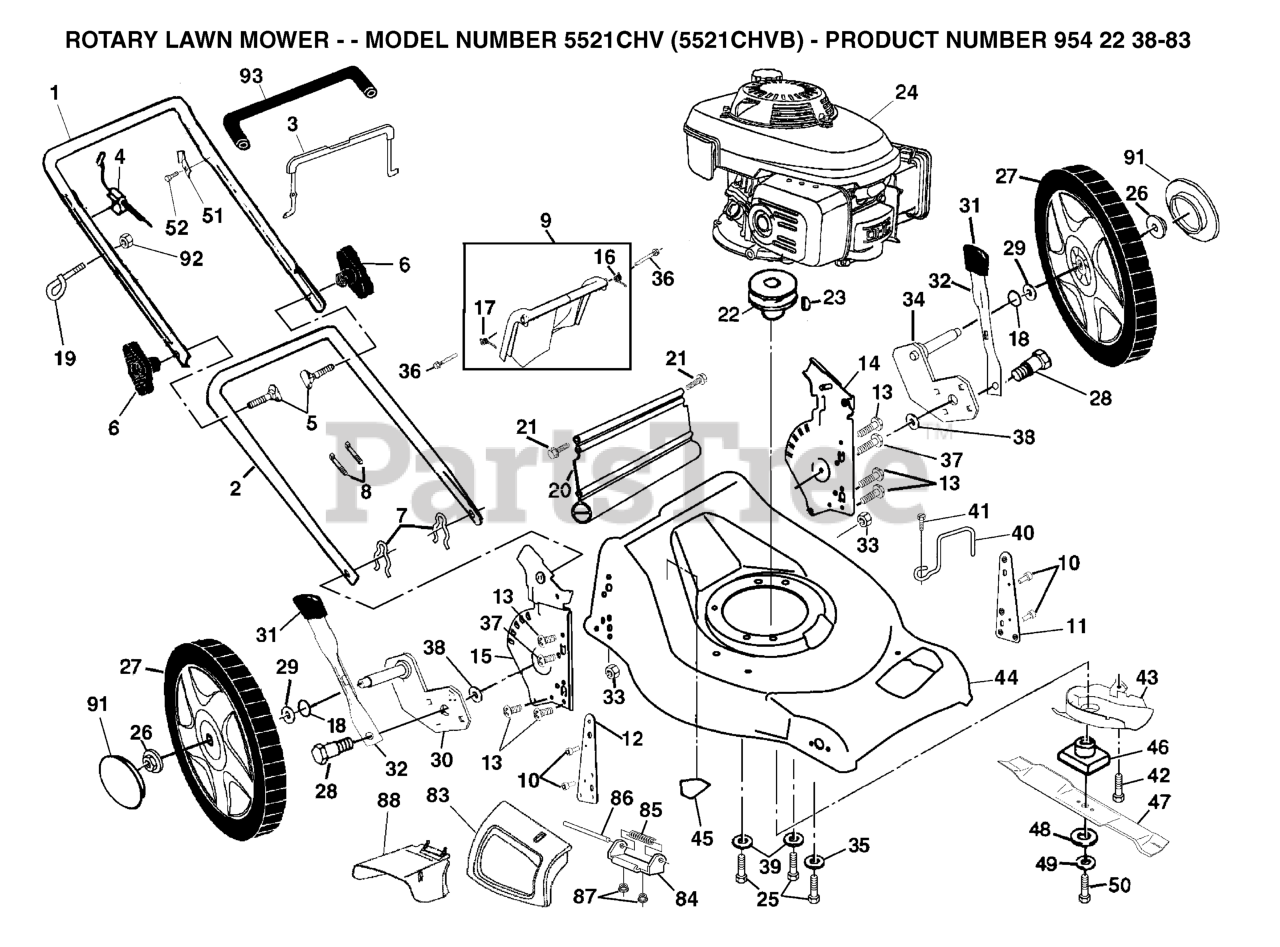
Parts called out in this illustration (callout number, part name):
1	UPPER HANDLE W/ GRIP
2	LOWER HANDLE
4	ENGINE ZONE CONTROL CABLE
5	HANDLE BOLT
7	HAIRPIN COTTER
8	TIE GUIDE
9	KIT.DOOR.RR.ASM.21.FWGD
10	RIVET BLIND
11	SUPPORT BRACKET LH
12	SUPPORT BRACKET RH
13	SCREW 14-20 X 5/8
14	HANDLE BRACKET ASSEMBLY, LEFT
15	HANDLE BRACKET ASSY. (RIGHT)
17	SPRING.REAR.DOOR.EZ.21
18	O-RING
19	ROPE, GUIDE
21	HINGE SCREW
22	ENGINE PULLEY
23	HI-PRO KEY
25	BOLT 3/8-16X1-1/8
26	HEX FLANGE LOCKNT
27	RP WHEEL 14X2
28	SHOULDER BOLT
29	WASHER.FLAT.1/2
30	AXLE ARM ASSEMBLY RR
32	SELECTOR SPRING
33	NUT.71038.31-18.HEX.NYLOCK
34	AXLE ARM ASSEMBLY LR
35	WASHER.ENGINE.BZP
37	SELF-TAPPING SCREW 5/16-18X3/4
38	SPACER.34X1.38X.22
39	WASHER,HARDEN
40	KEEPER, BELT
41	BOLT.HEX.HDWSH.5/16-18X1.00
42	SCREW
43	DEBRIS.SHIELD.FWGD.WALK.MOWER
45	DECAL HYT
46	BLADE ADAPTER
47	BLADE.21.PUSH/RWGD/FWG
48	WASHER,HARDEN
49	LOCKWASHER
50	SCREW, HEX HD 3/8-24 X 1-3/8
51	BRACKET UPSTOP
83	DOOR.MULCH.21.REAR.FWGD
84	BRACKET.ASM.HINGE.21.FWGD.
85	SPRING
86	ROD.HINGE.21
87	LOCKNUT.NYLOC.1/4-20
88	DEFLECTOR.CLIPPIN.21.FGD
91	HUBCAP
92	NUT
93	GRIP, FOAM
